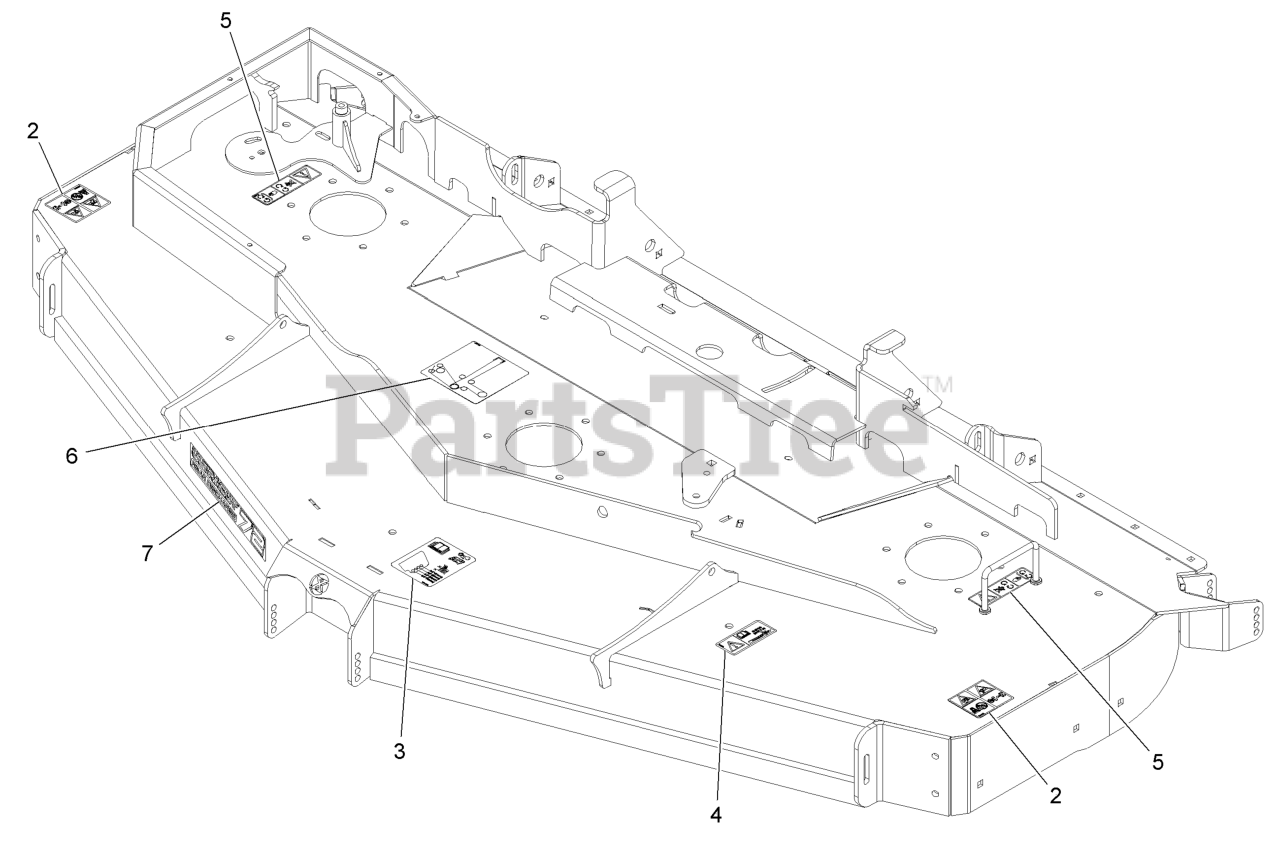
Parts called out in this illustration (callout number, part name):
3	DECAL-ROLLER, ANTI-SCALP
4	DECAL-BOLT TORQUE
5	DECAL-COVER, MISSING
6	DECAL,BELT ROUTING RD DEC
7	Decal, 72Rd
